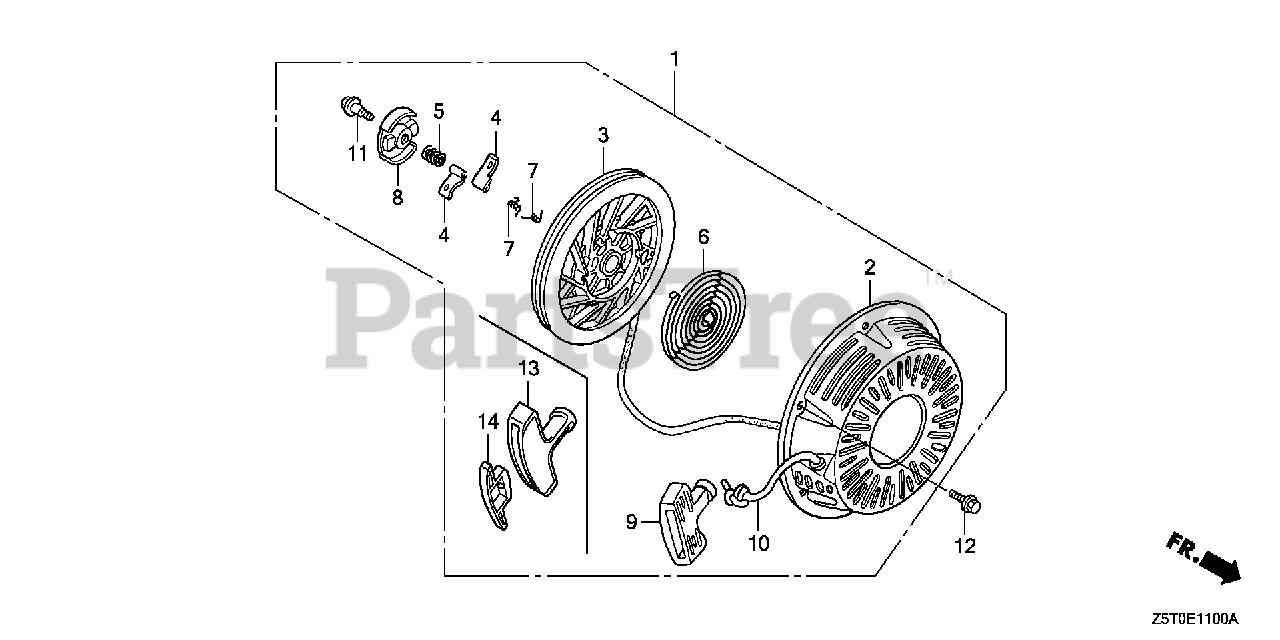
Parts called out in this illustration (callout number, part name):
1	STARTER ASSY., RECOIL *R280* (POWER RED)
2	CASE, RECOIL STARTER *R280* (POWER RED)
3	PULLEY, RECOIL STARTER
4	RATCHET, STARTER
5	SPRING, FRICTION
6	SPRING, STARTER RETURN
7	SPRING, RATCHET
8	RETAINER, SPRING
9	GRIP, STARTER
10	ROPE, RECOIL STARTER (#6X64") (N/A: USE P/N 08560-ZG921-11)
11	SCREW, CENTER
12	BOLT, FLANGE (6X10)
